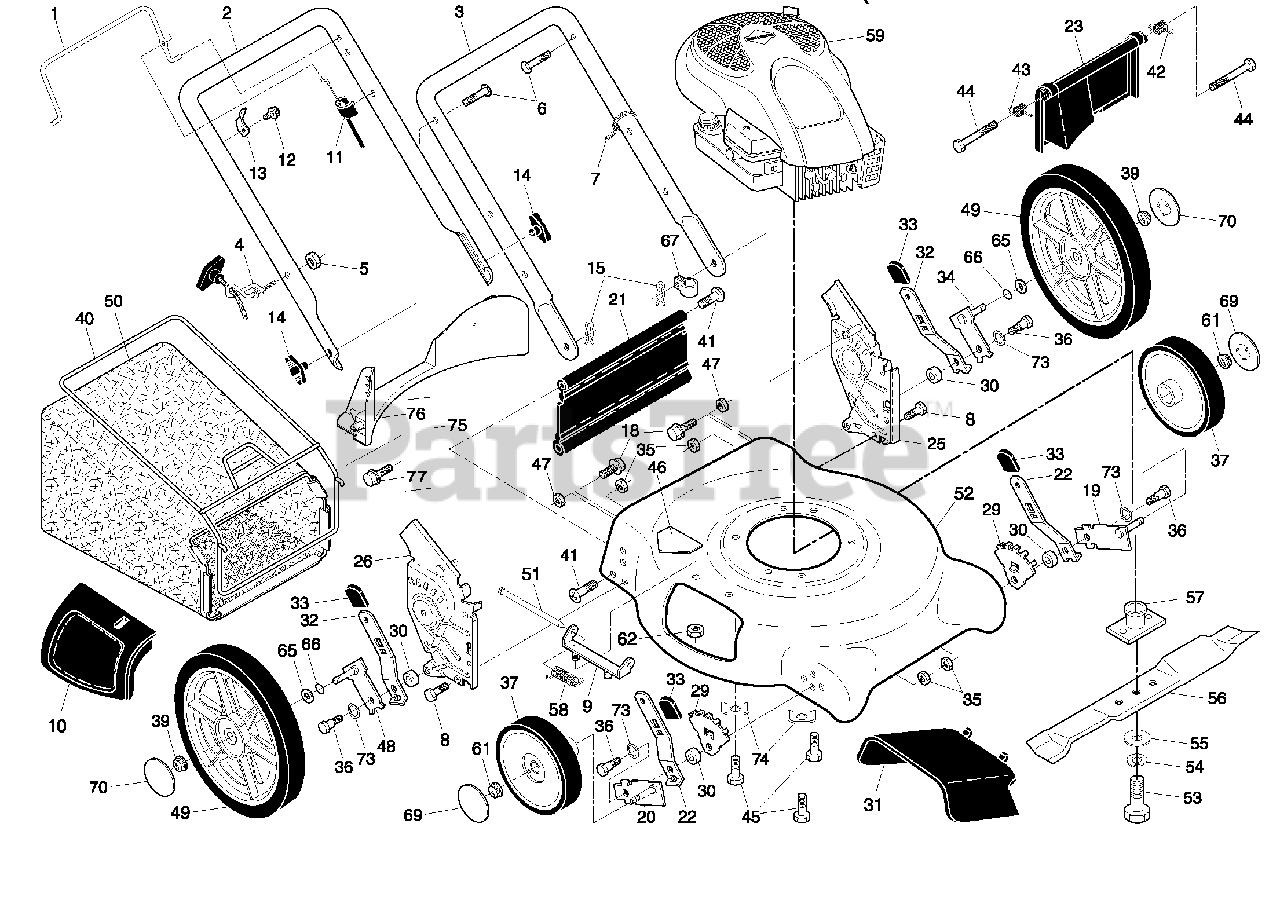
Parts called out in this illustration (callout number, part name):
1	Control Bar
2	Upper Handle
3	Lower Handle
4	Rope Guide
5	Locknut, Hex 1/4-20
6	Handle Bolt
7	Wire Tie
8	Hex Bolt 5/16-18 x 3/4
9	Mounting Bracket, Mulcher Door
10	Mulcher Door
11	Engine Zone Control Cable
12	Hex Washer Head Screw #10-24 x 1/2
13	Up-Stop Bracket
14	Handle Knob
15	Hairpin Cotter
18	Screw
19	Axle Arm Assembly, Front, LH
20	Axle Arm Assembly, Front, RH
21	Kit, Rear Skirt
22	Selector Spring, Front
23	Rear Door Assembly
25	Handle Bracket, LH
26	Handle Bracket, RH
29	Wheel Adjusting Bracket
30	Spacer
31	Deflector, Discharge
32	Selector Spring, Rear
33	Selector Knob
34	Axle Arm Assembly, Rear, LH
35	Locknut, Hex 5/16-18
36	Shoulder Bolt 5/16-18
37	Wheel & Tire Assembly, Front, 8"
39	Flanged Locknut
40	Frame, Grassbag
41	Hinge Screw
42	Spring, Rear Door, LH
43	Spring, Rear Door, RH
44	Bolt, Rear Door
45	Screw, Hex Head Thread Rolling Screw 3/8-16 x 1
46	Danger Decal
47	Nut, Hex
48	Axle Arm Assembly, Rear, RH
49	Wheel & Tire Assembly, Rear, 12"
51	Rod, Hinge
52	Kit, Lawn Mower Housing
53	Hex Head Screw, Grade 8, 3/8-24 x 1-3/8
54	Helical Lockwasher
55	Hardened Washer
56	21" Blade
57	Blade Adapter
58	Spring, Hinge Rod
61	Flanged Locknut
62	Nut, Hex
65	Washer, Flat 3/8
66	O-Ring
67	Clip, Cable
69	Hubcap, Front Wheel
70	Hubcap, Rear Wheel
73	Washer, Curved, Cylindrical
74	Washer, Special, Engine
75	Kit, Rear Baffle
76	Baffle, Rear
77	Screw, Rear Baffle
77	Operator's Manual, English
77	Operator's Manual, French
77	Repair Parts Manual
